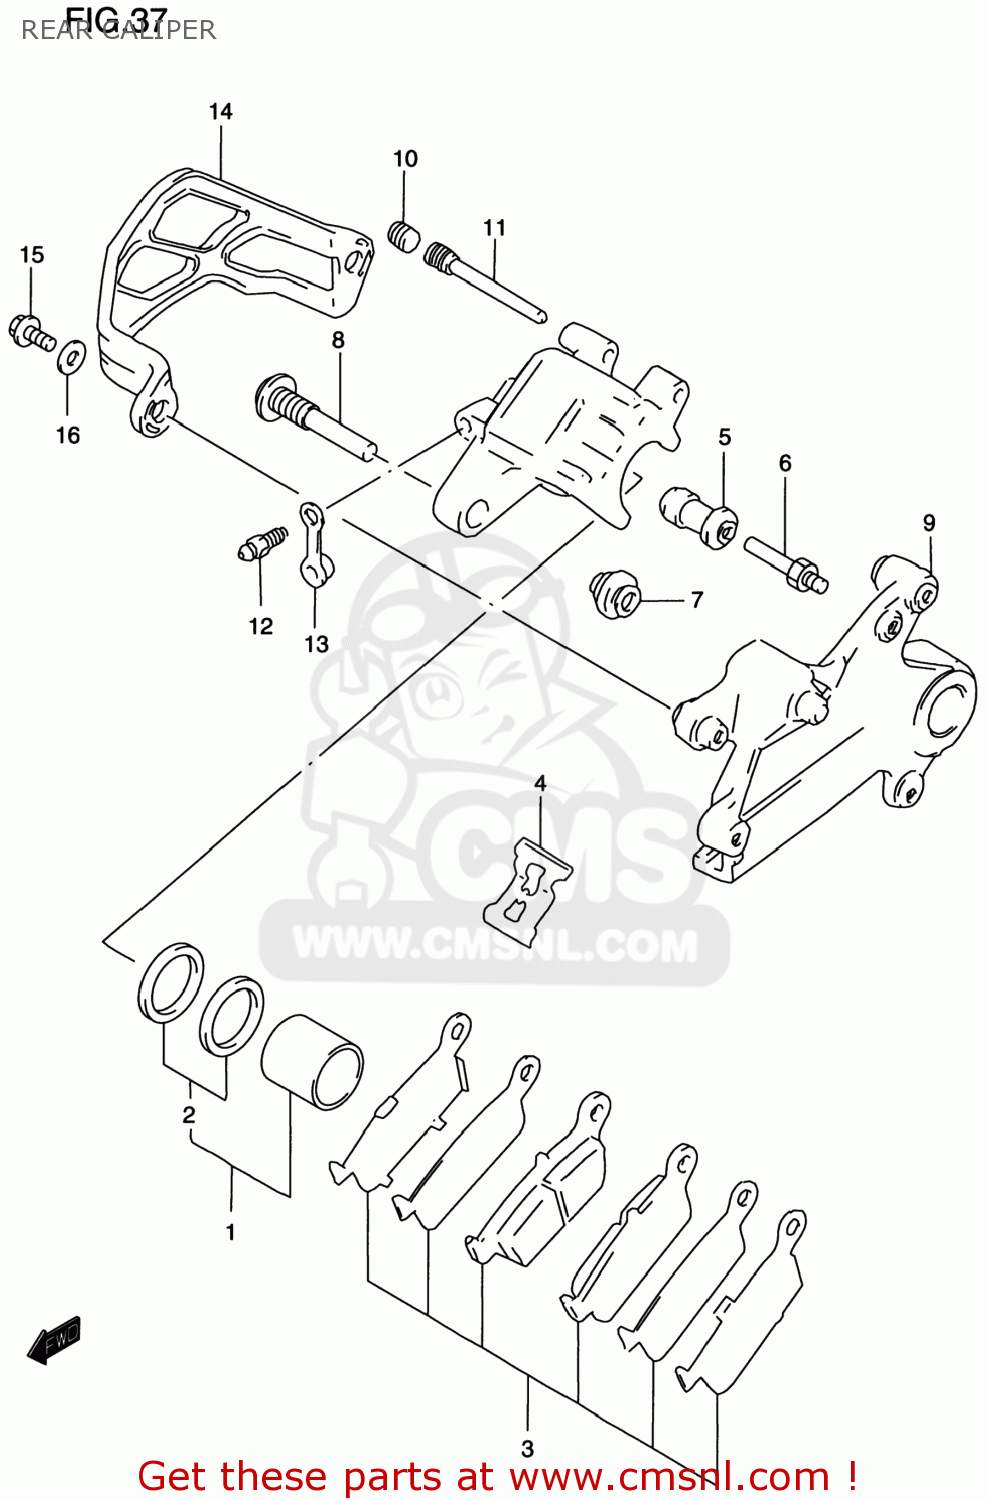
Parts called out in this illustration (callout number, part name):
1	PISTON SET
2	SEAL SET,PISTON
3	PAD & RETAINER SET
4	SPRING,PAD
5	BOOT
6	BOLT
7	BOOT
8	PIN,BOLT
9	BRACKET
10	PLUG,PIN
11	PIN,HANGER
12	BLEEDER
13	CAP,BLEEDER
15	GUARD,RR CALIPER
16	BOLT
17	WASHER
